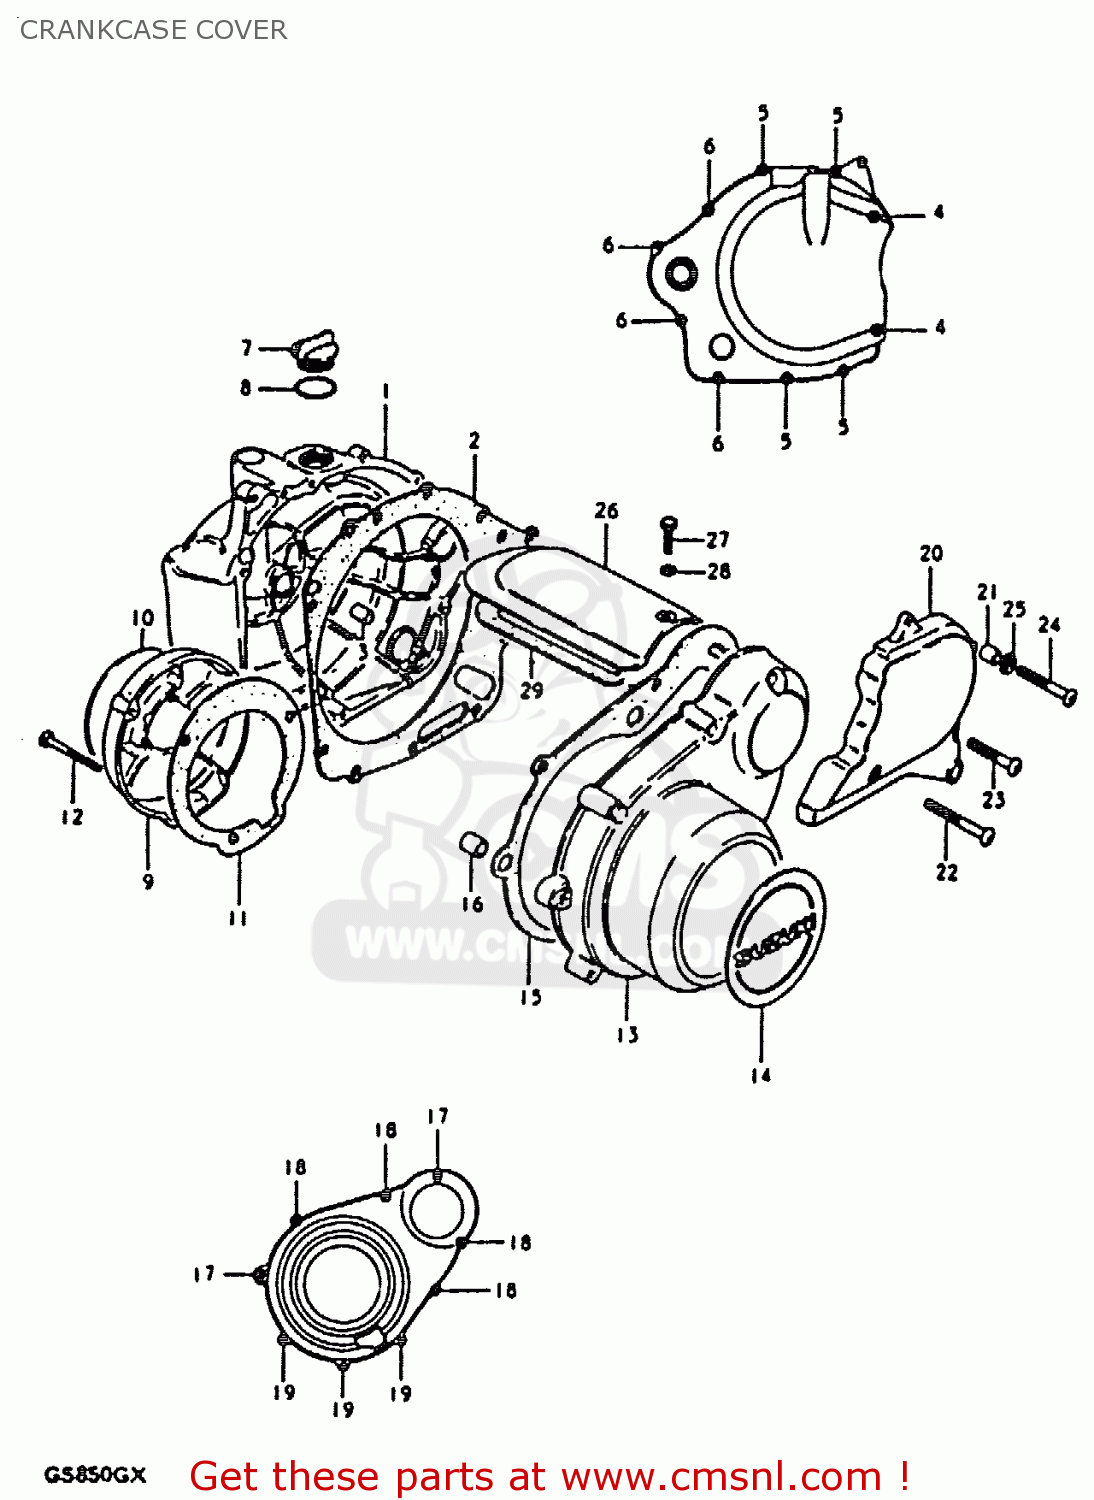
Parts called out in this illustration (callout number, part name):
1	COVER,CLUTCH
2	GASKET,CLUTCH COVER (MCA)
3	PIN
4	SCREW 6X65
5	SCREW
6	SCREW
7	CAP
8	O RING(D:2.2,ID:32)
9	COVER,CONTACT BREAKER
10	EMBLEM
11	GASKET,CONTACT BREAKER COVER (NAS)
12	SCREW
13	COVER
14	EMBLEM
15	GASKET,MAGNETO COVER (MCA)
16	PIN
17	SCREW (6X45)
18	SCREW
19	SCREW (6X35)
20	COVER,SPROCKET
21	PIN
22	SCREW 6X30
23	SCREW
24	SCREW
25	WASHER
26	COVER,STARTER MOTOR
27	BOLT
28	WASHER
29	GASKET,STARTER MOTOR COVER (MCA)
